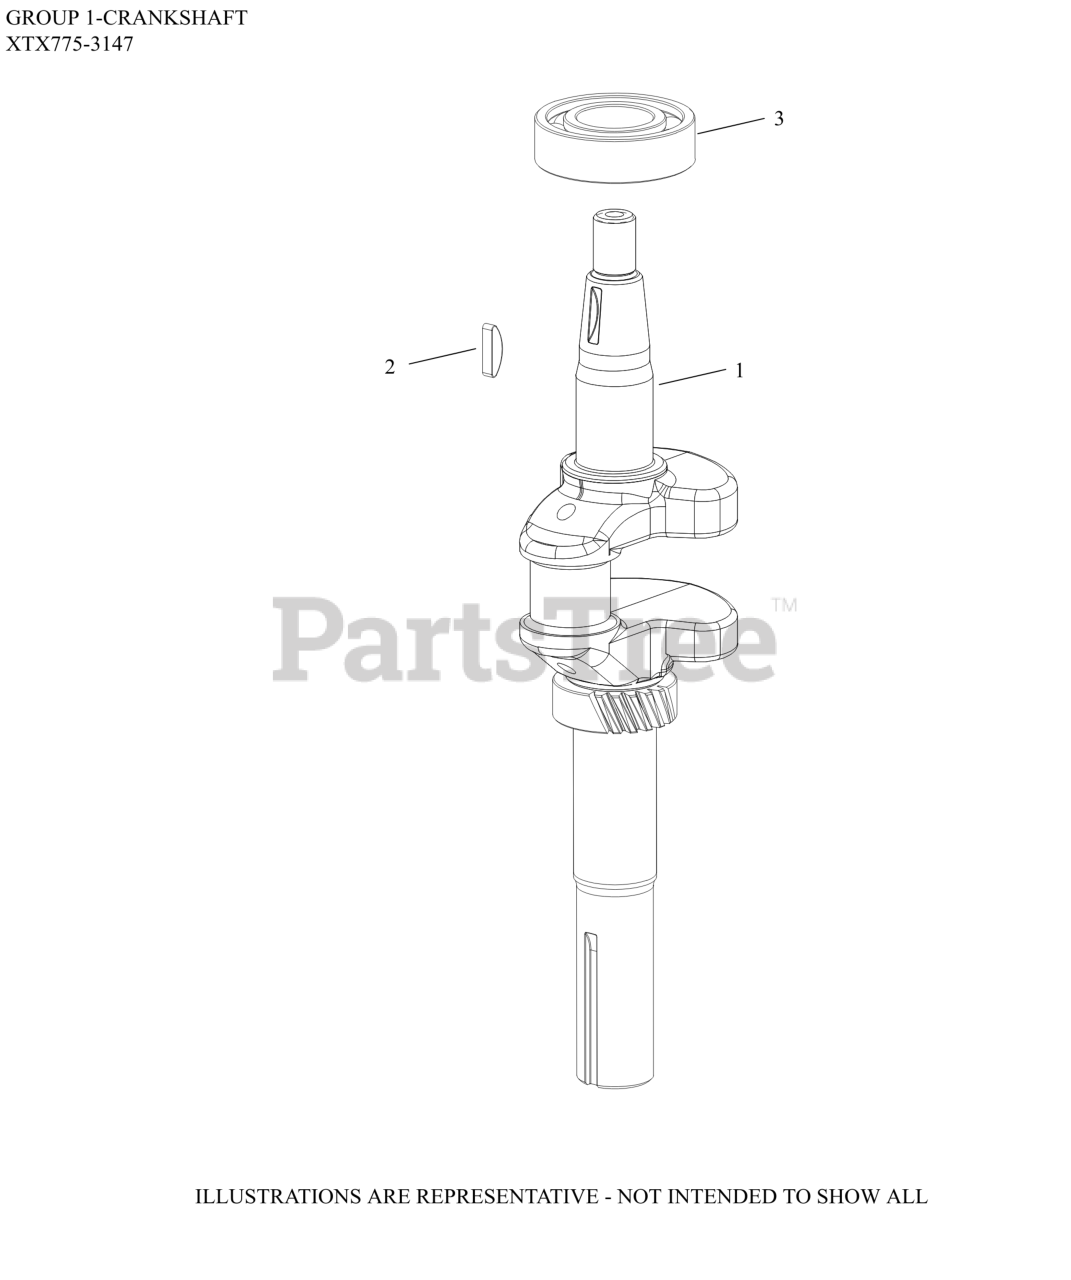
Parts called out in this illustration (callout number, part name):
1	CRANKSHAFT ASSEMBLY
2	KEY, FLYWHEEL
3	BEARING, BALL
